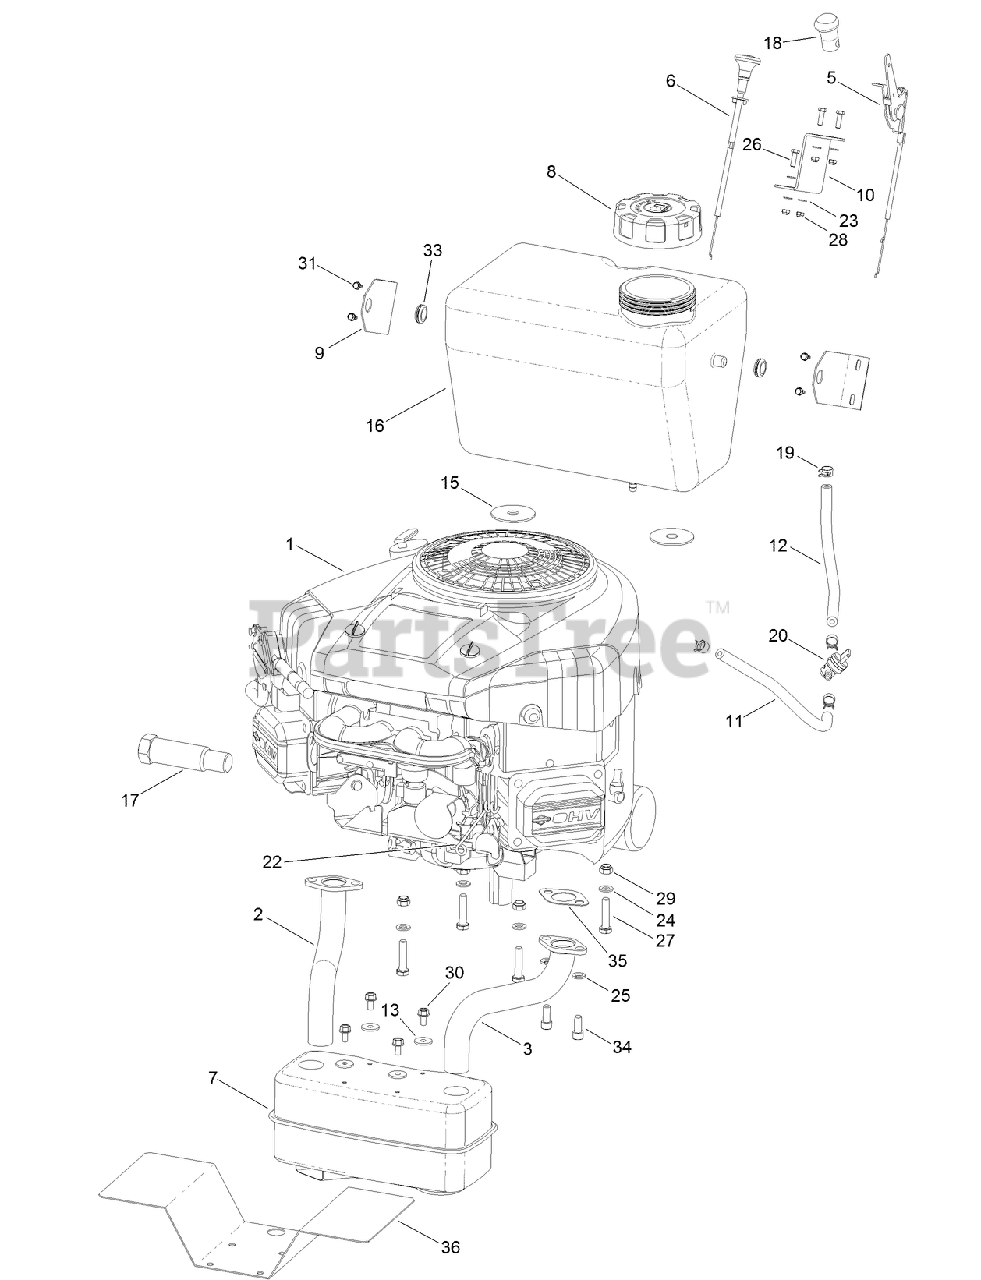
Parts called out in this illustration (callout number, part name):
2	TUBE-EXHAUST, RH
3	TUBE-EXHAUST, LH
5	CONTROL-THROTTLE, TWIN
6	CONTROL-CHOKE, TWIN
7	MUFFLER
8	CAP-FUEL
9	BRACKET-FUEL, TANK
10	HOLDER
11	LINE-FUEL
12	LINE-FUEL
13	WASHER-FLAT
15	WASHER-RUBBER
16	TANK-FUEL
17	COUPLER-DRAIN, OIL
18	KNOB-THROTTLE/CHOKE
19	CLAMP-LINE, FUEL
20	VALVE-TANK, FUEL
22	HOLDER-HARNESS, WIRING
23	WASHER
24	WASHER-PLAIN
25	WASHER-SPRING
27	SCREW-HH
28	NUT-LOCK
29	NUT-LOCK, NI
30	SCREW-HHTF
31	SCREW-TAP
33	BUSHING
34	SCREW-HH
35	GASKET-EXHAUST
36	COVER-TUBE
